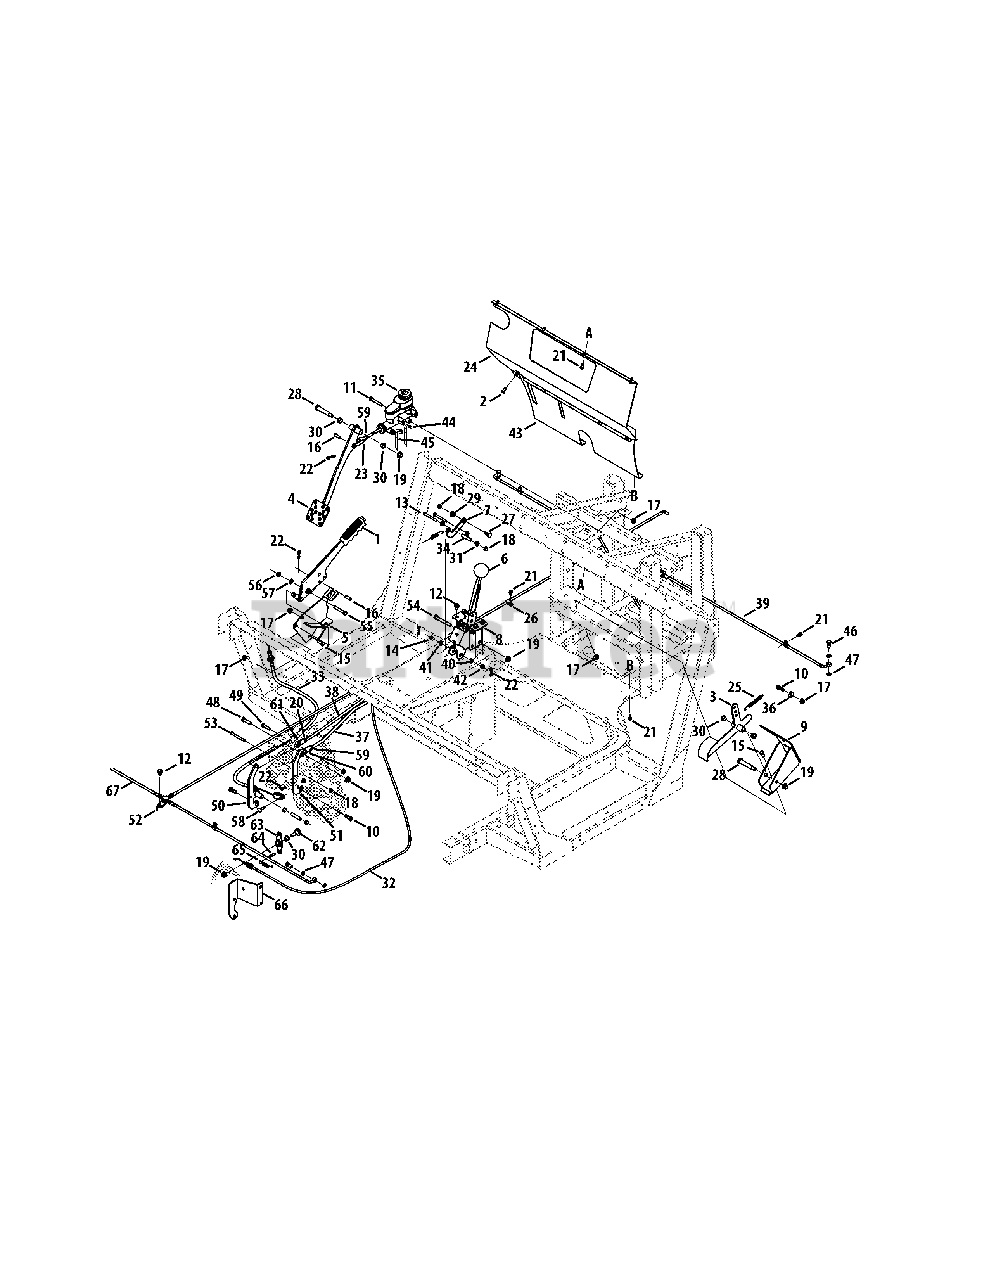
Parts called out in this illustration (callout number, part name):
1	Lever Assembly, Brake
2	Screw, ab, 1/4-14, 0.625,
3	Pedal Assembly, Accelerator
4	Pedal Assembly, Brake
5	Bracket Assembly, Park Brake
6	Shaft Assembly, Hurst, 4x4
6	Shaft Assembly, Hurst, 4x2
7	Plate, Pawl, Over Center
8	Shaft, Console Mount
10	Screw, Shldr, .372 x .375, 5/16-18
11	Screw, 5/16-18, 2.00, Gr5, Patch
12	Screw, Tt, 5/16-18, 0.500
13	Screw, 1/4-20, 2.25, Gr5, Std
14	Bearing., Flange, .315 ID
15	Screw, 5/16-18, .75, Gr5, Std
16	Pin, Clevis, 312 Od x 1.0"
17	Nut, Flange Lock, 5/16-18
18	Nut, Flange Lock, 1/4-20, Nylon
19	Nut, Flange Lock, 3/8-16, Nylon
20	Nut, Jam, 5/16-24, Gr5
21	Screw, Tt, 1/4-20 x .500
22	Pin, Cot, 3/32, 1.0
23	Yoke, 5/16-24
24	Panel, Dash, Upper
25	Spring, External, .38 Od x 3.6
26	Clamp, Hose
27	Screw, Shldr, .375x.380, 1/4-20
28	Screw, Shldr, .500 x 2.230, 3/8-16
29	Plastic Bushing .380 Id
30	Bearing, Flange, Nyliner, .500 x .34
31	Bearing, Flange, .375 x .580 x .250
32	Cable, Cont, Diff, Lock
33	Cable, Cont, Park, Brake, 4x4
34	Spacer, Pivot, Diff Lock
35	Cylinder, Master, Tandem
36	Washer, Flat, .349 x .879 x .063
37	Link, Shaft, F N R
38	Link, Shaft, Hi Lo, 4x4
39	Hose, brake, front
40	Washer, Flat, .385 x .62 x .063
41	Washer, Flat, .330 x .630 x .0635
42	Bearing, Flange, .377 Id
43	Panel, Dash, Lower, 4x4
44	Hose, Brake, Master Cyl, Front
45	Hose, Brake, Master Cyl, Rear
46	Fitting, Banjo Ftg Bolt, M10 x 1.00
47	Fitting, Banjo Ftg Crush Washer
48	Screw, 3/8-16 x 1.25
49	Screw, 5/16-18 x 1.25
50	Lever, Assembly, Shift, Hi-Lo, 4x4
51	Lever, Assembly, Shift, F N R
52	Fitting, Tee, -3, 45 Deg Flare
53	Screw, 1/4-20 x 2.50
54	Screw, 3/8-16 x 2.75
55	Screw, 5/16-18 x 2.00
56	Nut, Hex, 5/16-18
57	Washer, Flat, .344 x .688 x .065
58	Pin, Clevis
59	Nut, Jam, 3/8-24
60	Rod, End, 3/8 ID
61	Rod, End, 5/16 ID
62	Shoulder Screw, .500 dia x .434
62	Shoulder Bolt, .500 x .434
63	Lever, Assembly, Diff Lock
65	Spring, external, .38od x 2.10
66	Bracket, diff, Cable,mnt
67	Hose, brake, rear
